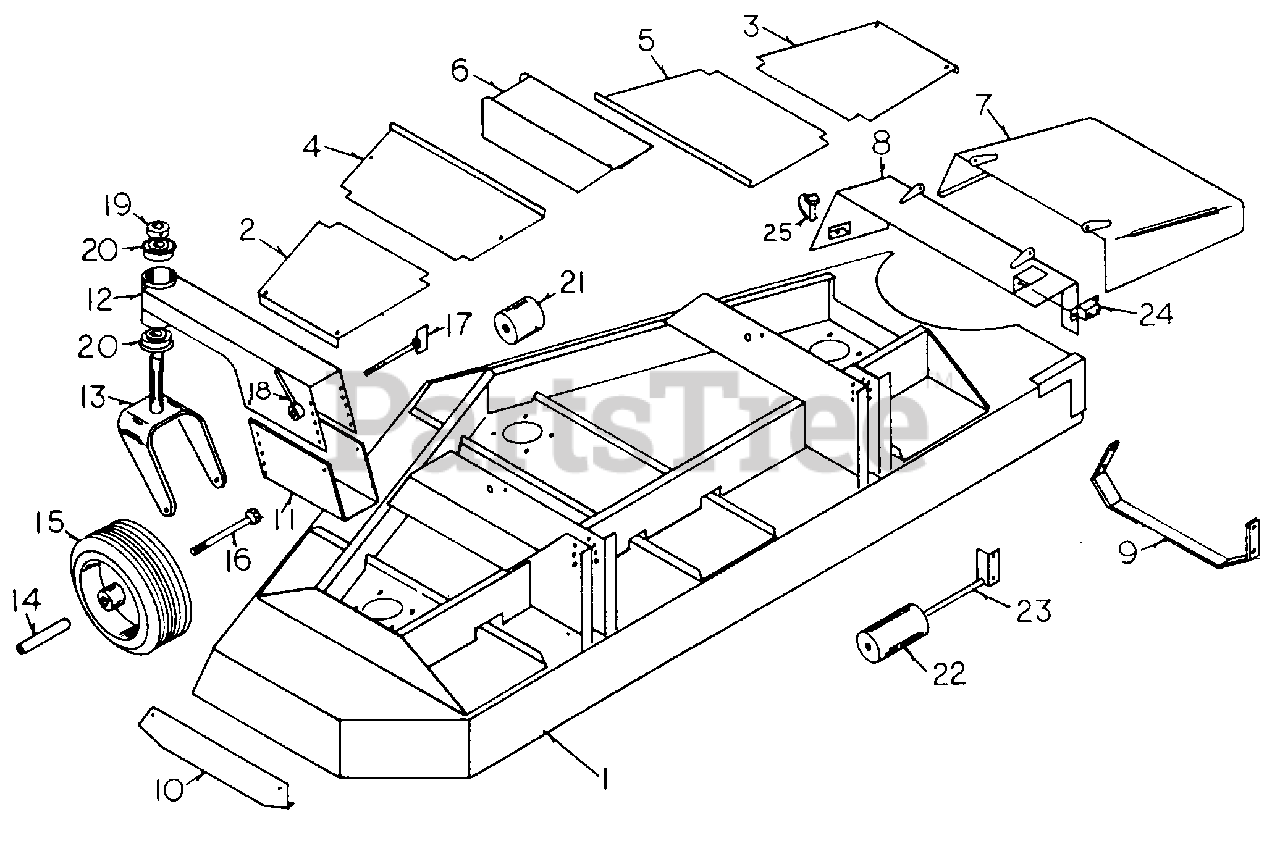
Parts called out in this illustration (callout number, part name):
1	Deck, 62"
2	Outside Cover, LH
3	Outside Cover, RH.
4	Center Cover, LH
5	Center Cover, RH.
6	Drive Shaft Cover
7	Fas-tatch Foot Cuard
8	Fas-tatch Foot Guard Mount
9	Shoe, RH Side
11	Gauge Wheel Mount Bracket
12	Gauge Wheel Mount
13	Gauge Wheel Fork
14	Axle 2
15	Wheel Assembly
16	Hex Bolt, 1/2-13 x 6 1/2"
21	Short Anti-scalp Roller
22	Long Anti-scalp Roller
23	Shaft & Bracket
24	10 Amp Circuit Breaker
